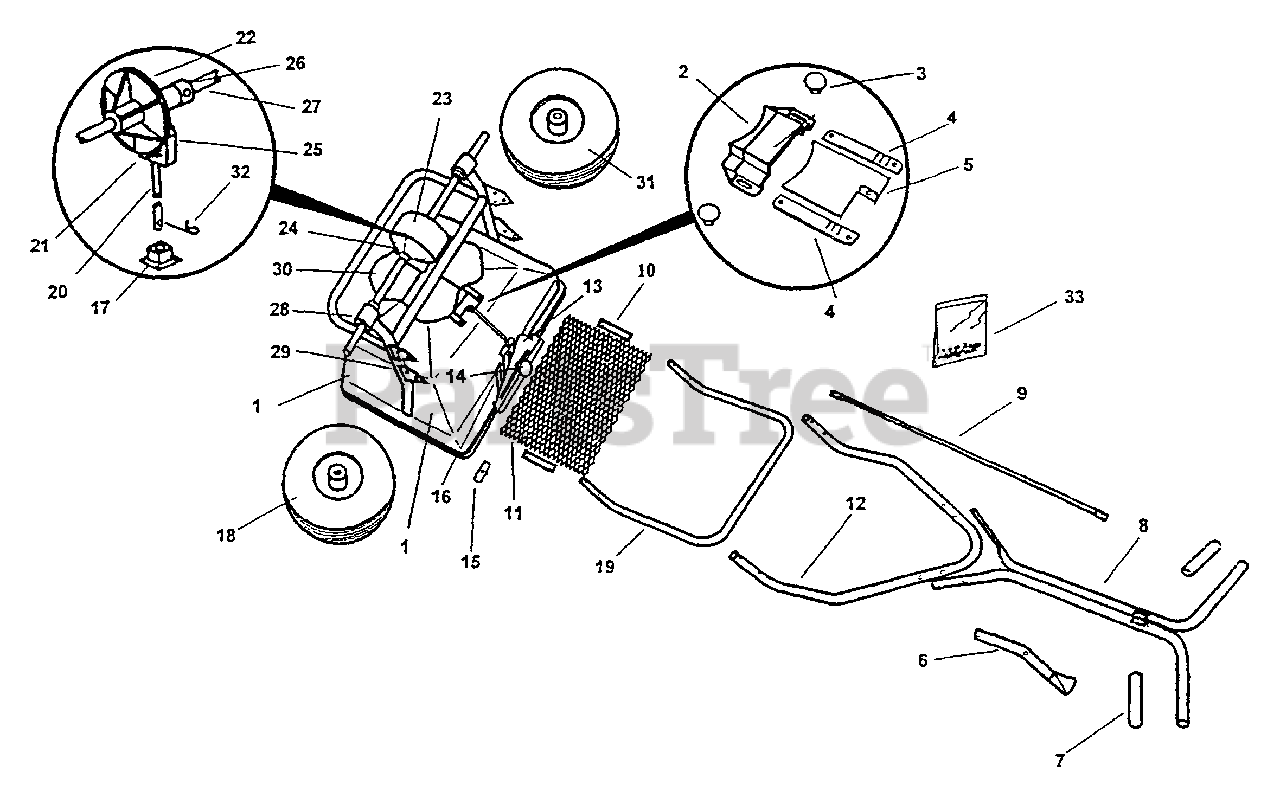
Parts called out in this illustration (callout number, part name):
1	HOPPER ASSY
2	CHUTE, DISCHARGE
3	DISCHARGE CHUTE KNOB
5	PLATE, SHUTOFF
6	HANDLE LEVER ASSY
7	GRIP, HANDLE
8	HANDLE - UPPER
9	TUBE, CONTROL
10	CLIP
11	SCREEN, HOPPER
12	BRACE, HANDLE
13	RATE PLATE
14	DIAL, RATE CONTROL
15	POINTER
16	SPRING HOUSING ASSY
17	BEARING
18	WHEEL - DRIVE
19	LEG
20	WASHER - 3/4"
21	GEAR - SHAFT
22	GEAR, AXLE
23	COVER, GEAR
24	CLAMP, GEAR COVER
25	SUPPORT, GEAR
26	AXLE COLLAR W/ SET SCREW
27	AXLE
28	BEARING, AXLE
29	FRAME
30	IMPELLER
31	WHEEL, FREE
32	AGITATOR
33	WASHER - 5/8"
